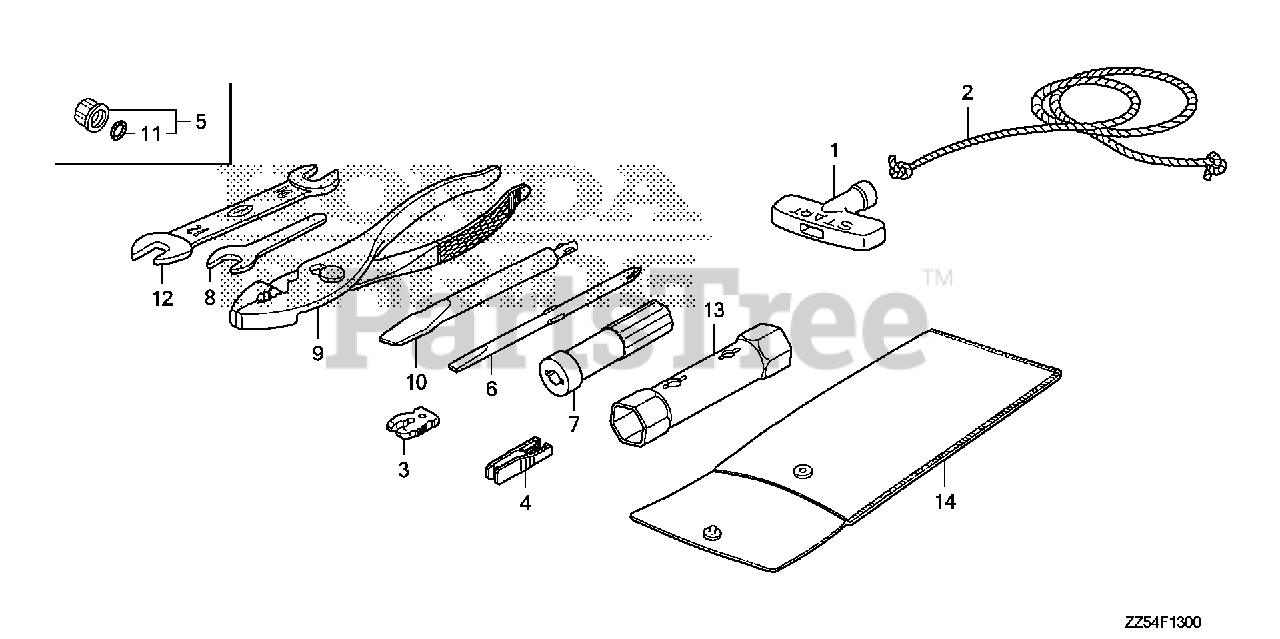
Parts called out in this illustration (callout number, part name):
1	GRIP, STARTER
1	KNOB, RECOIL SRARTER
2	ROPE, RECOIL STARTER (1300MM)
3	CLIP, EMERGENCY LOCK
4	PULLER, MINI FUSE (SUMITOMO)
6	SCREWDRIVER (NO.2 PHILLIPS -)
8	SPANNER (8MM) (NOT AVAILABLE)
9	PLIERS (135) (RIKEN)
10	SCREWDRIVER, CHECK BOLT
12	SPANNER (10X12)
13	WRENCH, BOX (P18X19)
